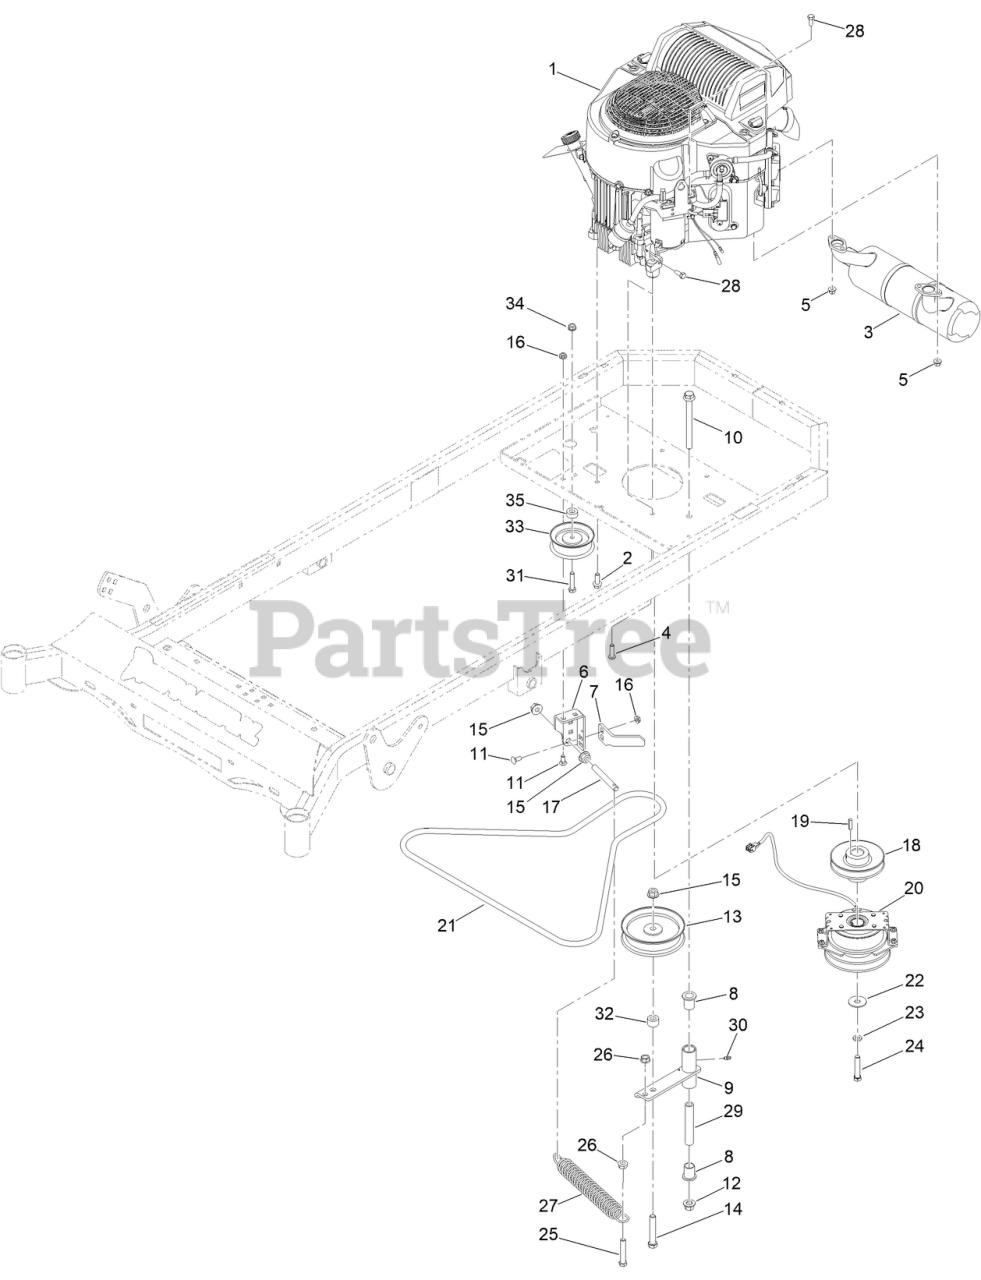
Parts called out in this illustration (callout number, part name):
1	KAWASAKI FR730V-DS27-R ENGN
2	3/8-16 X 1-1/8 IND HWH W/SERR TRI LOB ZY
3	2019 EXHAUST SYST FOR KAWI FR FS AND FT
4	3/8-16 X 1-1/4 PAN TORX (TRI-LOB) TRS ZC
5	NUT-HF
6	MWR PUMP IDLER TENSIONING BRKTPAINTED
7	2021 TTQ MWR OGURA CLUTCH BRKT PAINT
8	3/4IN ID X15/16IN OD X 1-1/8IN FLNG BUSH
9	MWR PUMP IDLER ASSY PAINTED
10	1/2-13 X 5-1/2 HEX FLANGE BOLT GR 8 ZY
11	BOLT-CARR
12	NUT-LOCK
13	5-3/4IN IDLER PULLEY 7/16IN SPACER ASSY
14	1/2-13 X 3 HEX C/S GR 5 ZINC W/LOCTITE
15	NUT-HHF
16	NUT-HF
17	MWR PUMP IDLER SPRING TENSIONER
18	MWR HYDRAULIC PUMP DRIVE PULLEY (B-BELT)
20	MWR TTQ OGURA CLUTCH
21	MWR TTQ PUMP BELT
22	1/2IN X 1-5/8 BELLEVILLE CUP WASHER YZ
23	WASHER-LOCK
24	TTQ CLUTCH BOLT
26	NUT-HF
27	MWR DECK SPRING
28	M8-1.25 X 20MM HEX FLANGE BOLT ZINC 10.9
29	MWR INNER IDLER SPACER
30	1/4IN DRIVE TYPE GREASE FITTING YZ
31	SCREW-HH
32	.530 ID/ 1IN OD X .625 PUMP IDLER SPACER
33	4IN DIESEL AND ECONOMY MWER IDLER PULLEY
34	NUT-HHF, WHIZ
35	MWR PULLEY SPACER
